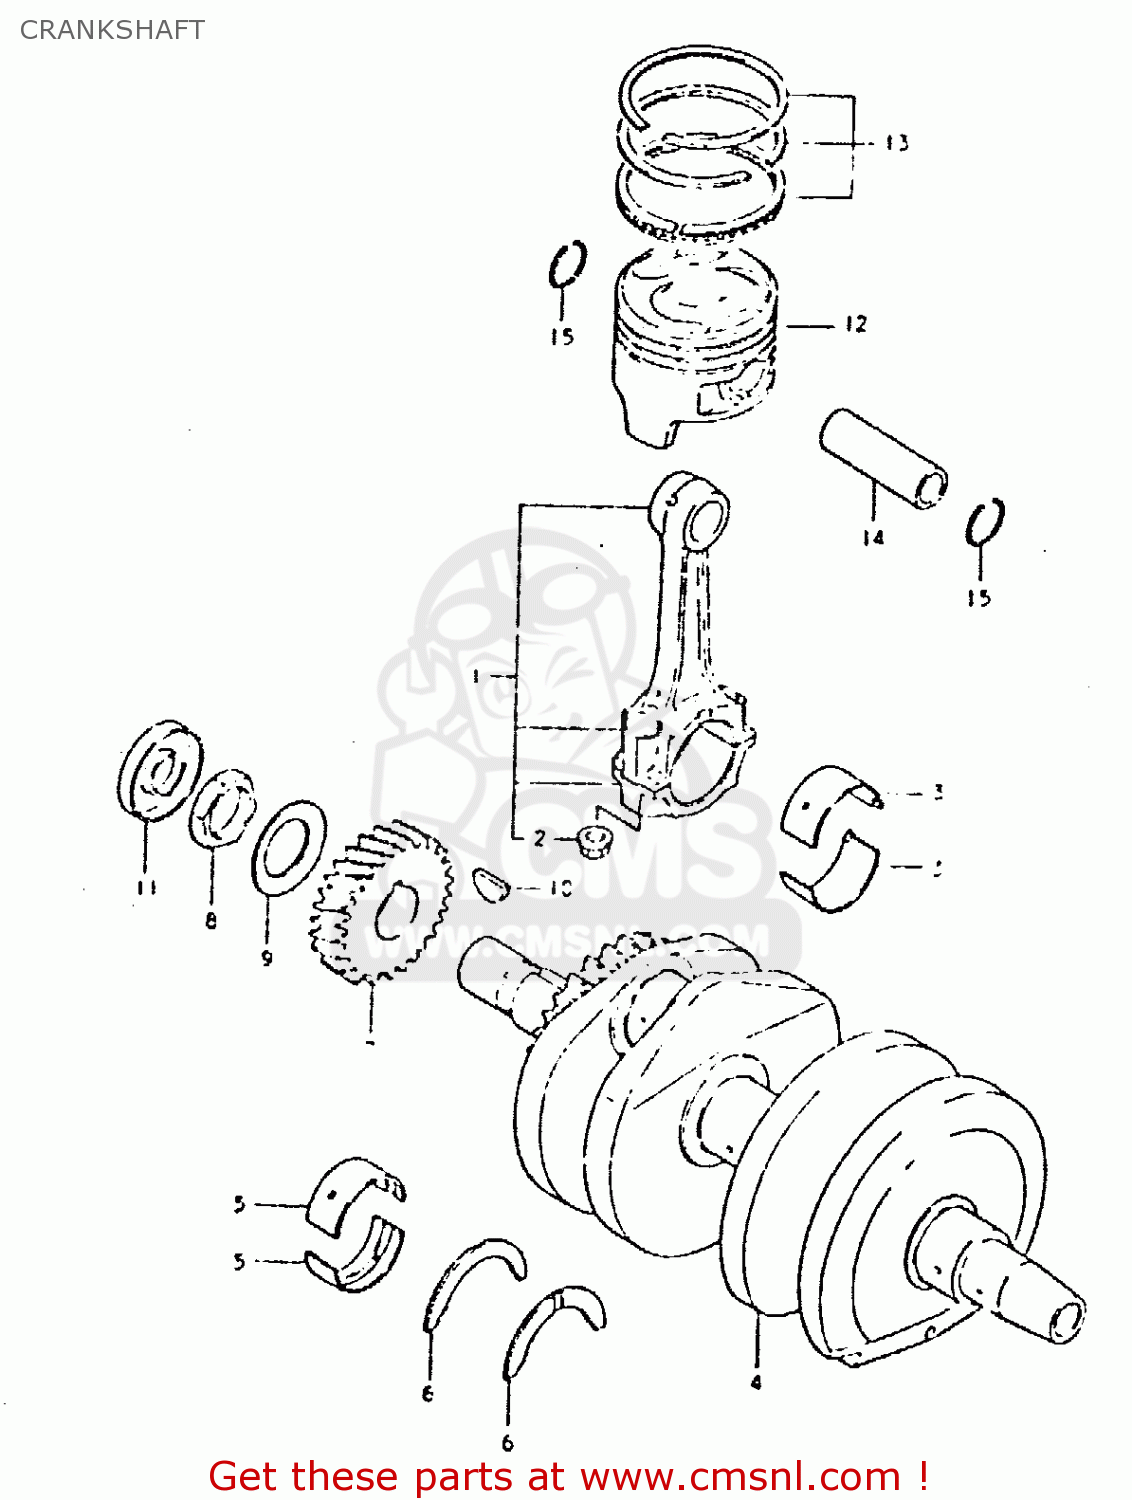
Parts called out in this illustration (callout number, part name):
1	ROD ASSEMBLY,CONNECTING
2	NUT
3	BEARING,CRANK PIN
4	CRANKSHAFT
5	METAL CRANKSHAFT
6	BEARING,CRANK THRUST
7	GEAR,PRIMARY DRIVE NO.28
8	NUT
9	WASHER
10	KEY
11	OIL SEAL
12	PISTON (STD)
13	RING SET,PISTON
14	PIN,PISTON
15	CIRCLIP,PISTON PIN
